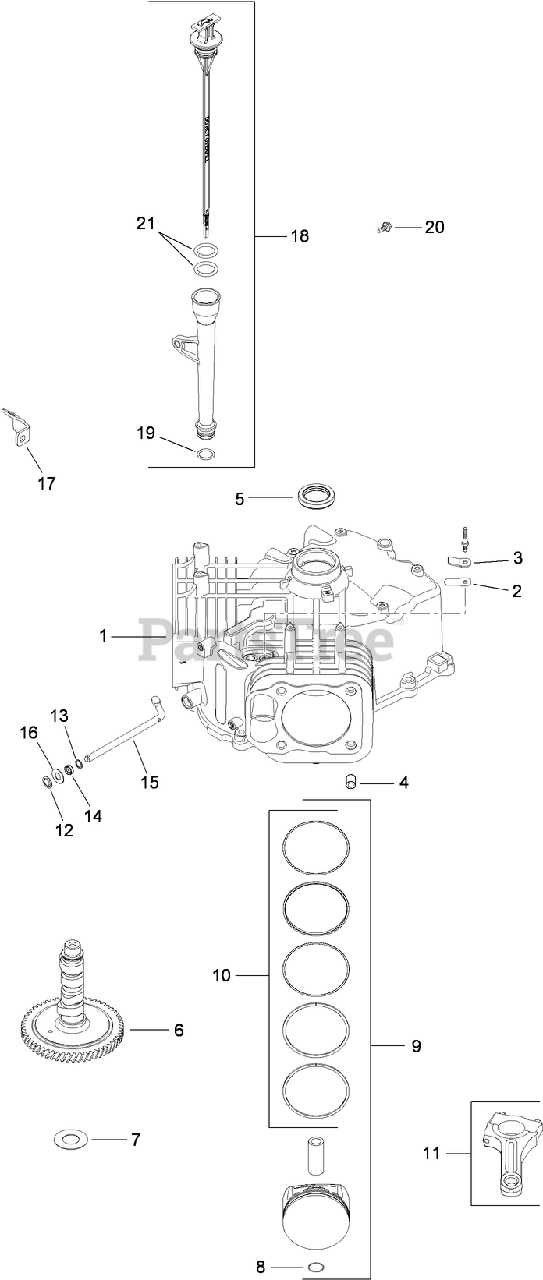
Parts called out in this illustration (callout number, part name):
1	SHORTBLOCK (SV710-740)
2	REED-BREATHER
3	RETAINER-REED, BREATHER
4	PIN-LOCATING
5	SEAL-OIL (HELIX LIP)
6	CAMSHAFT KIT (INCLUDES 25 357 14-S)
7	SHIM-CAMSHAFT (WHITE .028)
7	SHIM-CAMSHAFT (BLUE .03)
7	SHIM-CAMSHAFT (RED .032)
7	SHIM-CAMSHAFT (YELLOW .034)
7	SHIM-CAMSHAFT (GREEN .036)
7	SHIM-CAMSHAFT (GRAY .038)
7	SHIM-CAMSHAFT (BLACK .04)
8	RETAINER-PIN, PISTON
9	PISTON W/RING SET (STD) (INCLUDES REF 8, 17)
9	PISTON W/RING SET (.25) (INCLUDES REF 8, 19)
10	PISTON RING SET (STD)
10	PISTON RING SET (.25)
11	ROD-CONNECTING (STD)
12	RETAINER-RING
13	WASHER-FLAT (11/32)
14	SEAL-CROSS SHAFT, GOVERNOR
15	SHAFT-CROSS, GOVERNOR
16	WASHER-FLAT (9MM)
17	BRACKET-TUBE, OIL FILL
18	DIPSTICK AND TUBE ASM (INCLUDES REF 2, 31)
19	O-RING
20	SCREW-FLG, THD FRM (M5X0.8X13)
21	O-RING
